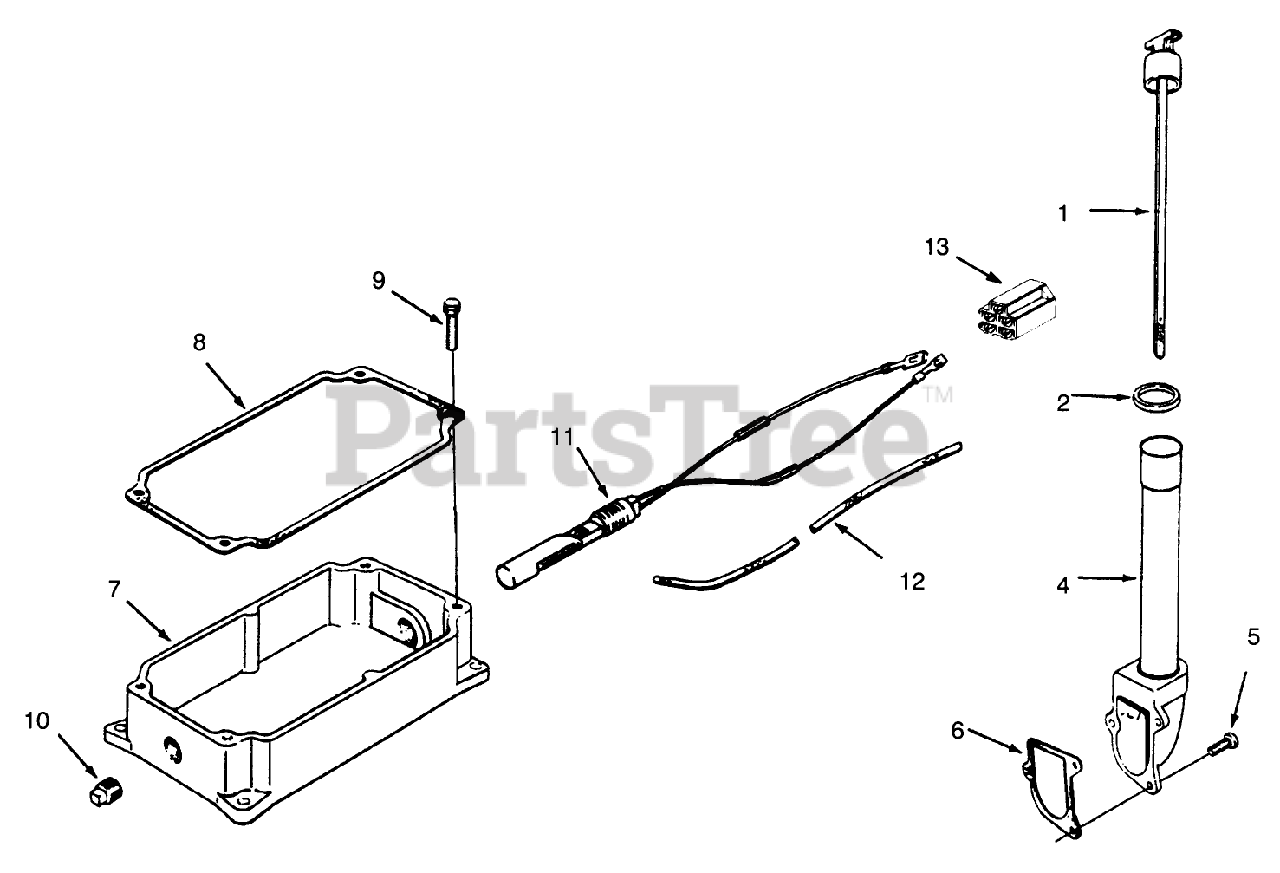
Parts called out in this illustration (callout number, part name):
1	KOHLER 47-038-27
2	KOHLER 41-153-01
4	KOHLER 47-029-06
5	KOHLER X-131-2
6	KOHLER 237064
7	KOHLER 45-199-05
8	KOHLER 235057
9	KOHLER X-159-3
10	KOHLER X-75-10
12	KOHLER 25-431-02
13	KOHLER 48-155-01
